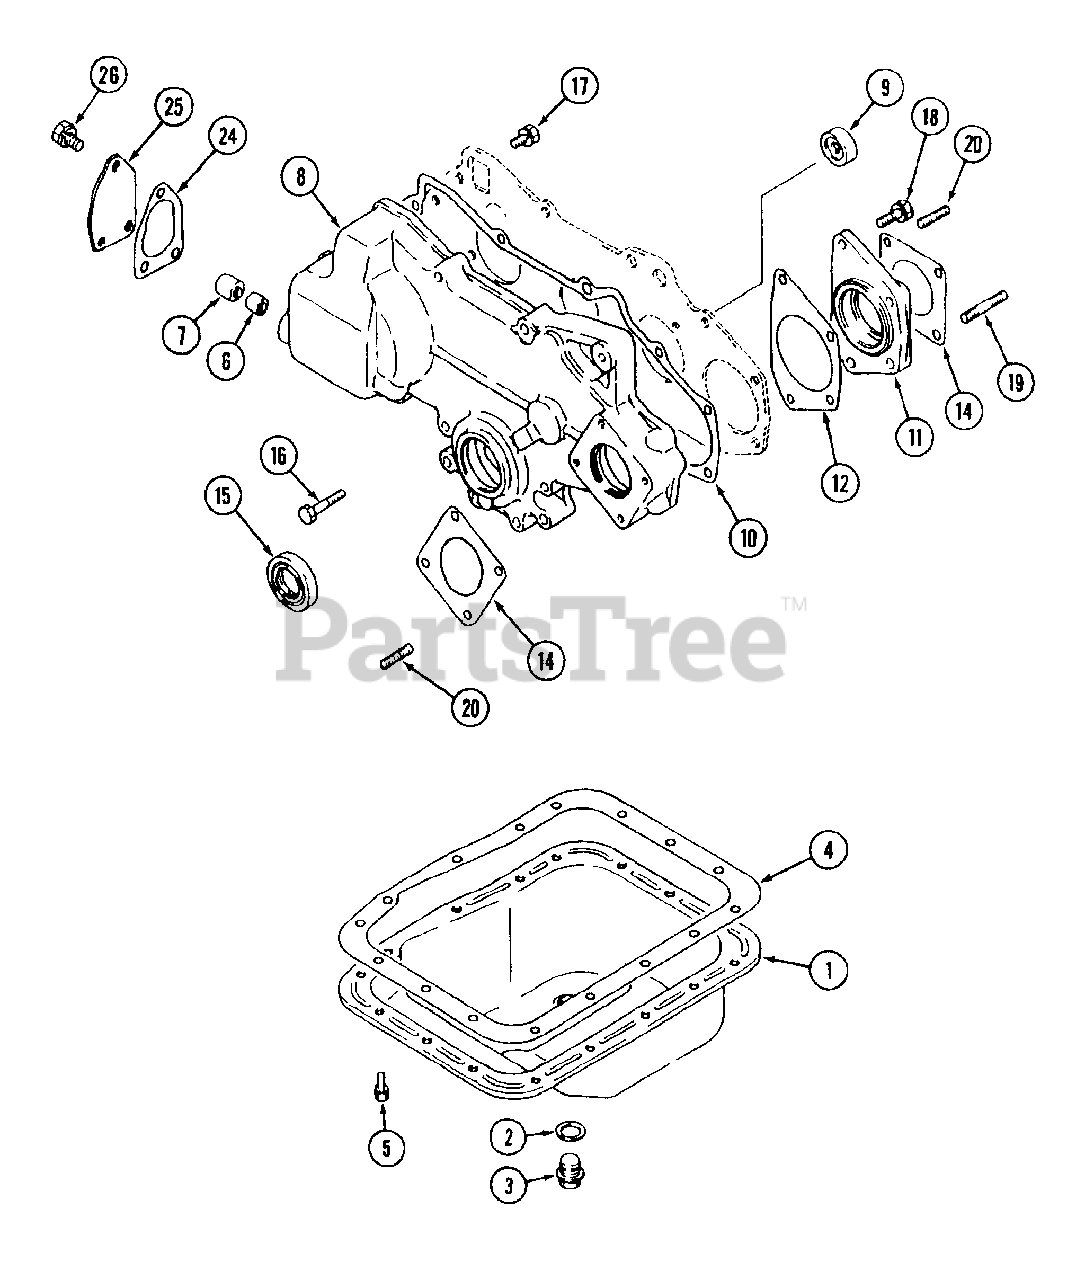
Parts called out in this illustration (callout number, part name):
1	Pan Ass'y., Oil
4	Gasket, Oil Pan
5	Bolt, w/Washer
6	Bearing, Needle
7	Bearing, Needle
10	Gasket, Gear Case
11	Housing, Gear Pump
12	Gasket, Housing
14	Gasket, Oil Pump Cover
17	Bolt, w/Washer
18	Bolt, w/Washer
24	Gasket, Governor Cover
25	Cover, Governor
26	Bolt, w/Washer
